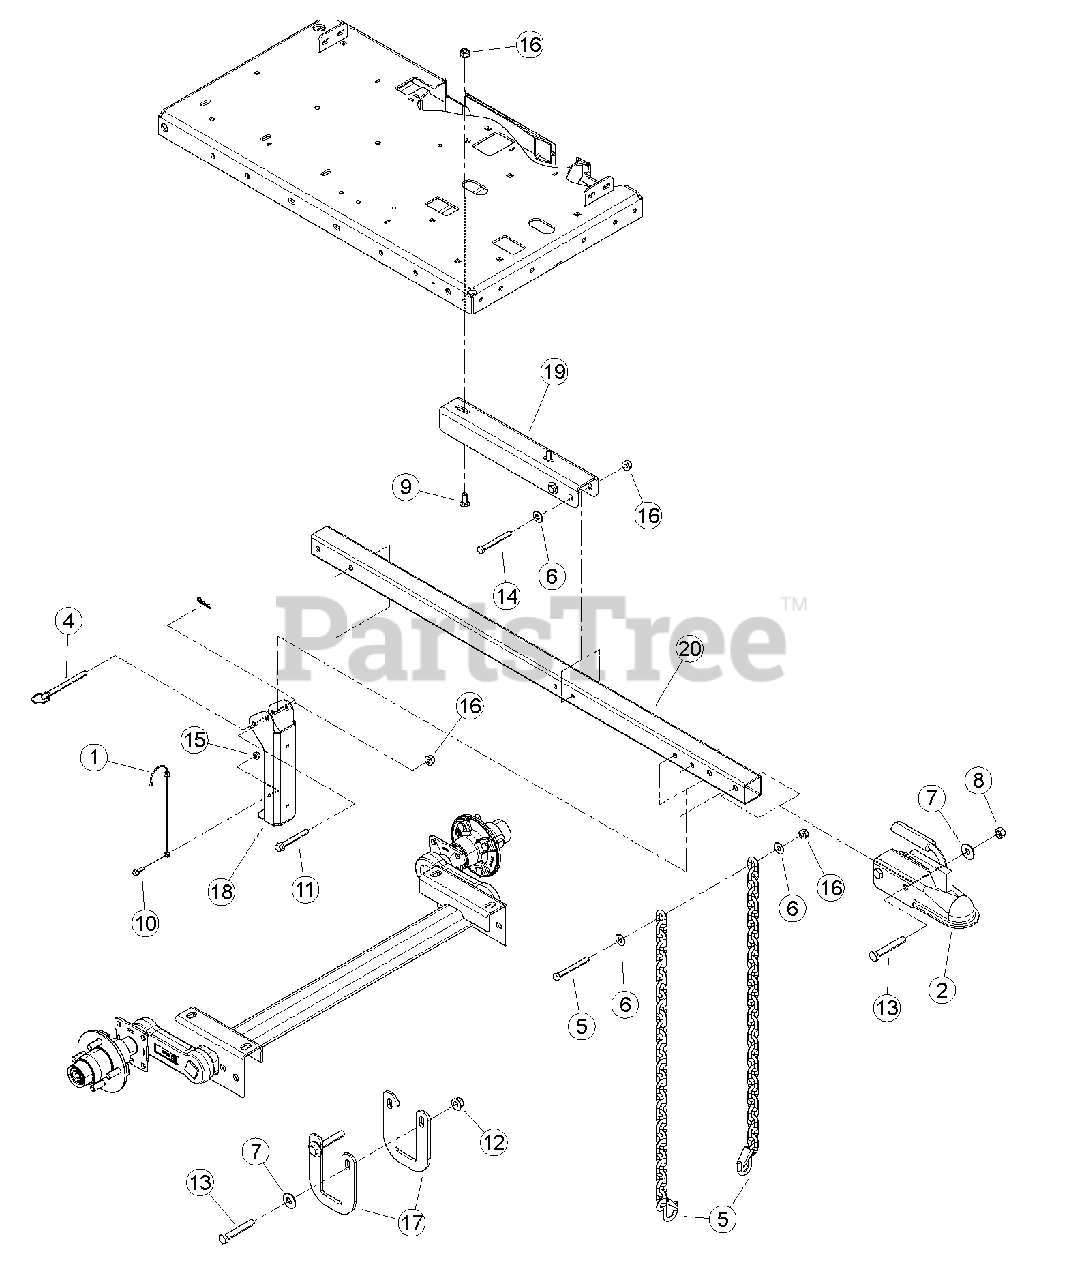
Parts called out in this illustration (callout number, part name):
1	LANYARD, NYLON
2	COUPLER, 50 MM BALL
3	CHAIN, SAFETY 5000 LB W/LATCH
4	PIN, 3/8 HITCH
5	BOLT, 3/8 X 3-1/2" HEXHD GR5 ZP
6	WASHER, 3/8" FLAT ZP
7	WASHER, 1/2" FLAT Z
8	NUT, 1/2" CENTERLOCK GRB ZP
9	BOLT, 3/8 X 1" CRG GR5 NC ZP
10	BOLT, 1/4-20 X 3/4 HWH GR5 CZP
11	BOLT, 3/8 X 3 FLANGE NC
12	NUT, 1/2-13 NYLOCK FLANGE
13	BOLT, 1/2 X 3-1/4 HCS GR5 ZP
14	BOLT, 3/8 X 3-1/4 HXHD GR5 ZP
15	NUT, 1/4-20 NYLOCK-FLANGE
16	NUT, 3/8-16 NYLOCK-FLANGE
17	PLATE, HITCH SADDLE
18	STAND, JACK
19	CHANNEL, HITCH POLE
20	TUBE, HITCH
